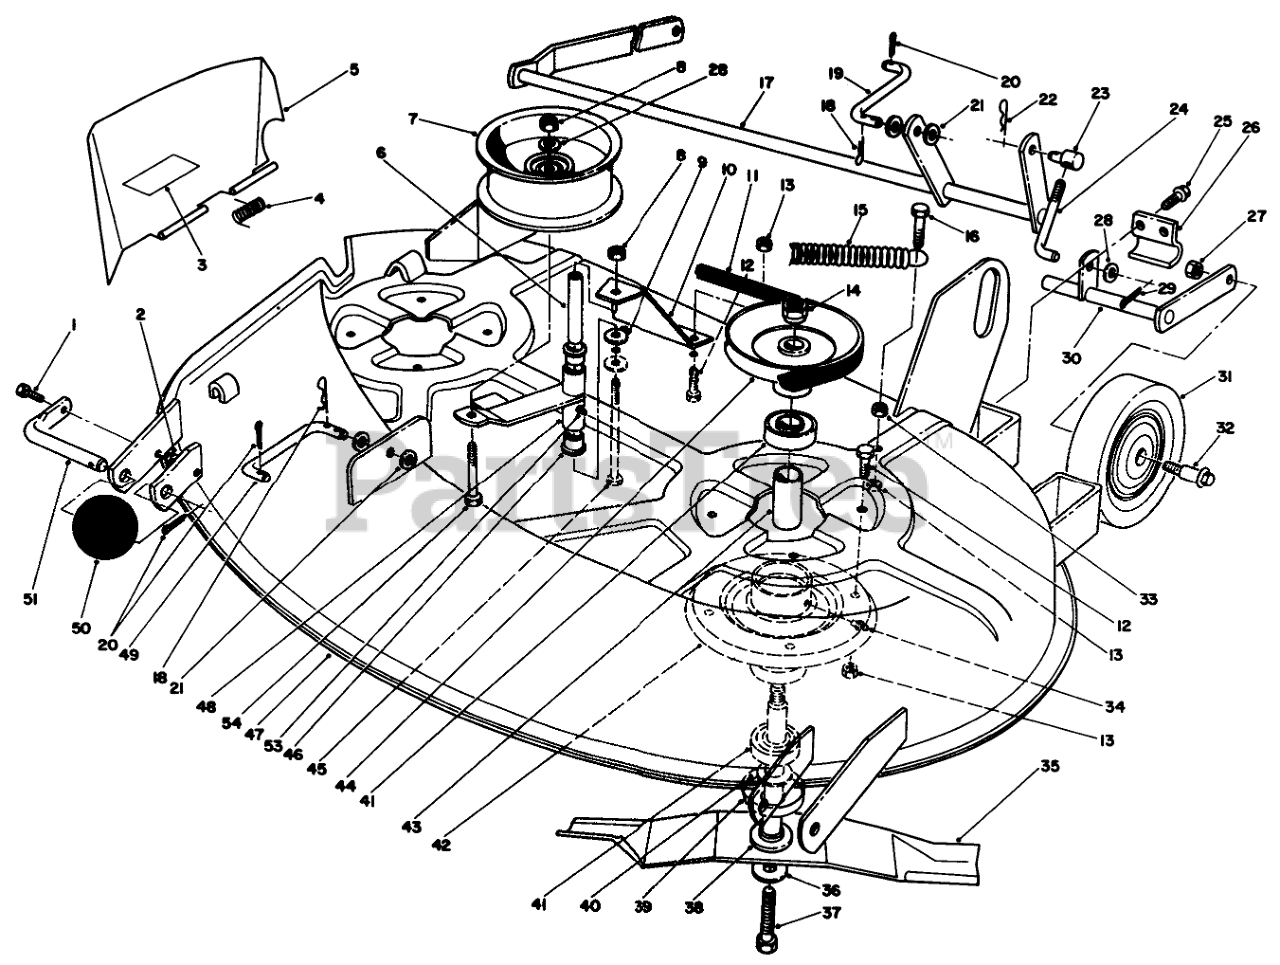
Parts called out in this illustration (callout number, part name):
1	Bolt
2	Nut
3	DECAL-DANGER, THROWN OBJECT
4	SPRING-TORSION
5	Deflector
6	SPACER
7	Pulley-Idler
8	NUT
9	WASHER
10	BRACE R
11	V-Belt
12	Bolt
13	Nut
14	Nut
15	SPRING-EXTENSION
16	Bolt
17	Shaft-R.H.
18	Hairpin
19	LINK-REAR
20	Cotter Pin
21	Washer
22	Hairpin
23	TRUNNION
24	ROD-LIFT
25	Bolt
26	Camp
27	Nut
28	Washer
29	Cotter Pin
30	Shaft-L.H.
31	WHEEL
32	BOLT-SHOULDER
33	Nut
34	Fitting-Grease
35	Blade
36	WASHER-BELLEVILLE
37	SCREW-HH
38	SHAFT-SPINDLE
39	SHIELD-BEARING
40	SPACER-HARDNED
41	BEARING-BALL
42	Housing-Spindle
43	SPACER
44	Pulley-Spindle
45	Bolt 3/8-16 x 4
46	BUSHING
47	Deck-Cutting Unit
48	Arm-Idler
49	LINK-FRONT
50	ROLLER
51	SHAFT-ROLLER
53	Grease Zerk
54	Bolt
